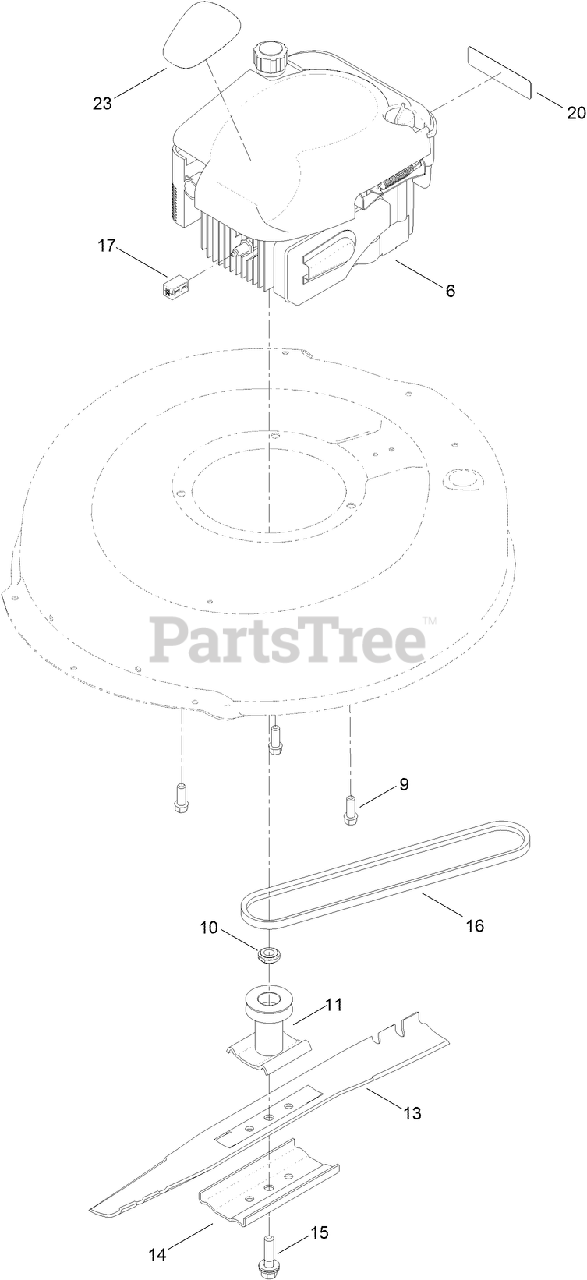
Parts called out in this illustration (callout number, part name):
9	SCREW-TAPTITE
10	SPACER-DRIVER
11	DRIVER-BLADE
14	SUPPORT-BLADE
15	BOLT-BLADE
17	FERRITE-CLAMP
20	DECAL-ARRESTER, SPARK
23	DECAL-SHROUD
